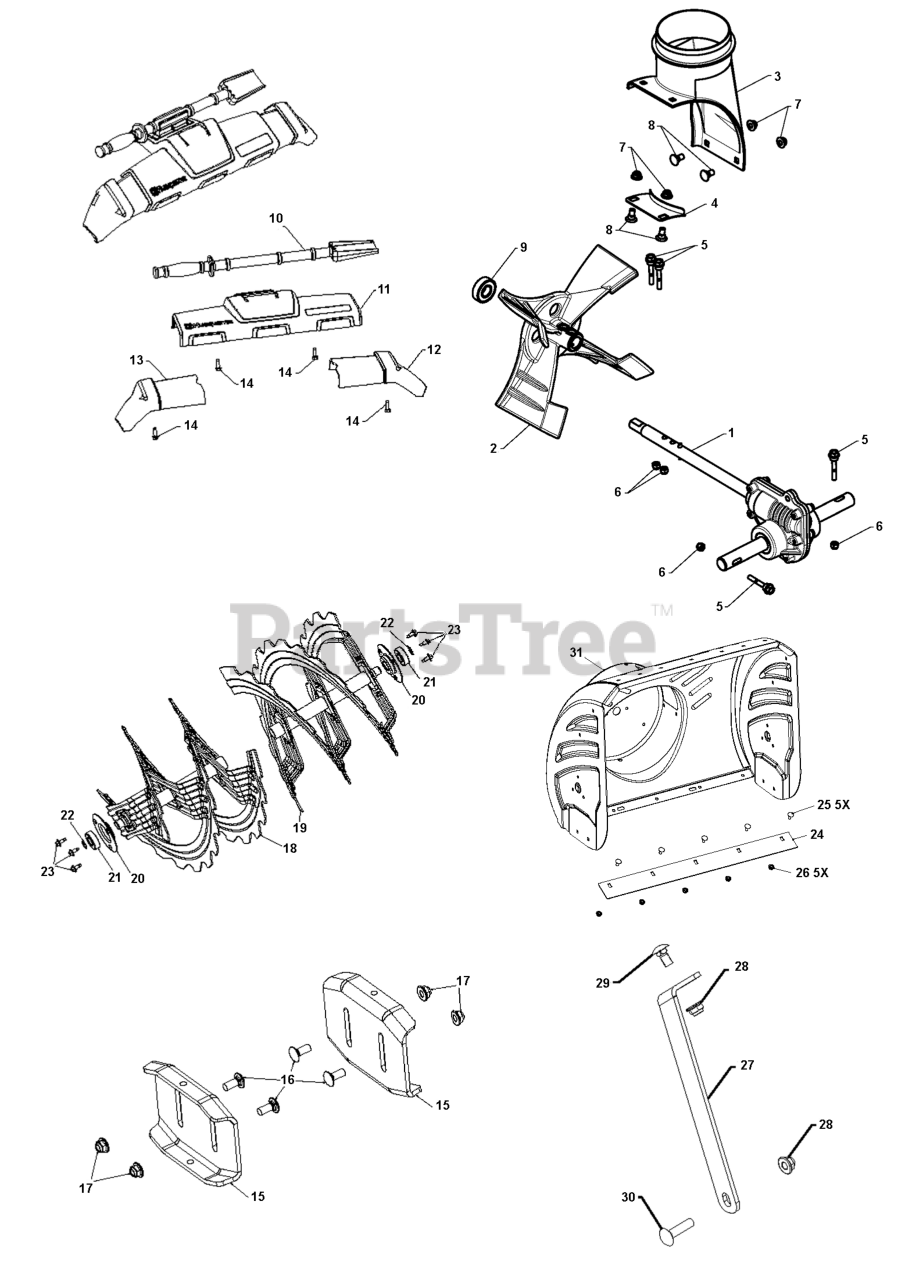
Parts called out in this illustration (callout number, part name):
1	GEARBOX CAST DD SHAFT
2	Blades
2	IMPELLER CAST.IRON.12IN MS 417
3	CHUTE.DISCHARGE.BASE
4	Brackets
4	BRACKET, CORNER DISCHARGE
5	BOLT SHEAR HX HD 1/4-20 CLEAR
6	NUT HEXAGON 1/4-20 ST ZPB
7	NUT HEX FLG NYLOCK BLK 5_16-1
8	BOLT CARR WAFER BLK 5_16-18 X
10	CLEAN OUT TOOL
11	TRIM AUGER FRONT TRIM ASSEMBLY
12	TRIM AUGER.HOUSING.WING.RH MS
13	TRIM AUGER.HOUSING.WING.LH MS
14	SCREW 14-20 X 5/8
14	SCREW HEXWSHR 1/4-20X3/4
15	SKID PLATE
16	BOLT CARR BLK 5_16-18 X .750
17	NUT HEX FLG NYLOCK BLK 5_16-1
18	AUGER.RIB.27.RH.LS.GREY
19	AUGER.RIB.27.LH.LS.GREY
20	SUPPORT.BEARING.SINGLE.STAGE.B
21	BEARING.BALL.MANDREL
22	RETAINING RING LT
23	SCREW HEXWSHR 1/4-20X3/4
24	PLATE.SHAVE.30.LS.SNOW.BLACK
24	PLATE.SHAVE.27.LS.SNOW.BLACK
25	BOLT ROUND HEAD SQUARE NECK BO
26	NUT.FLANGE.5/16
26	GSPW Hardware
27	NUT.FLANGE.5/16
28	NUT HEX FLG NYLOCK BLK 5_16-1
29	BOLT CAR BLK 5/16-18 X 5/8
30	BOLT.CARRIAGE.5/16-18
31	HOUSING ASSY KIT AUG.HSG.58618
